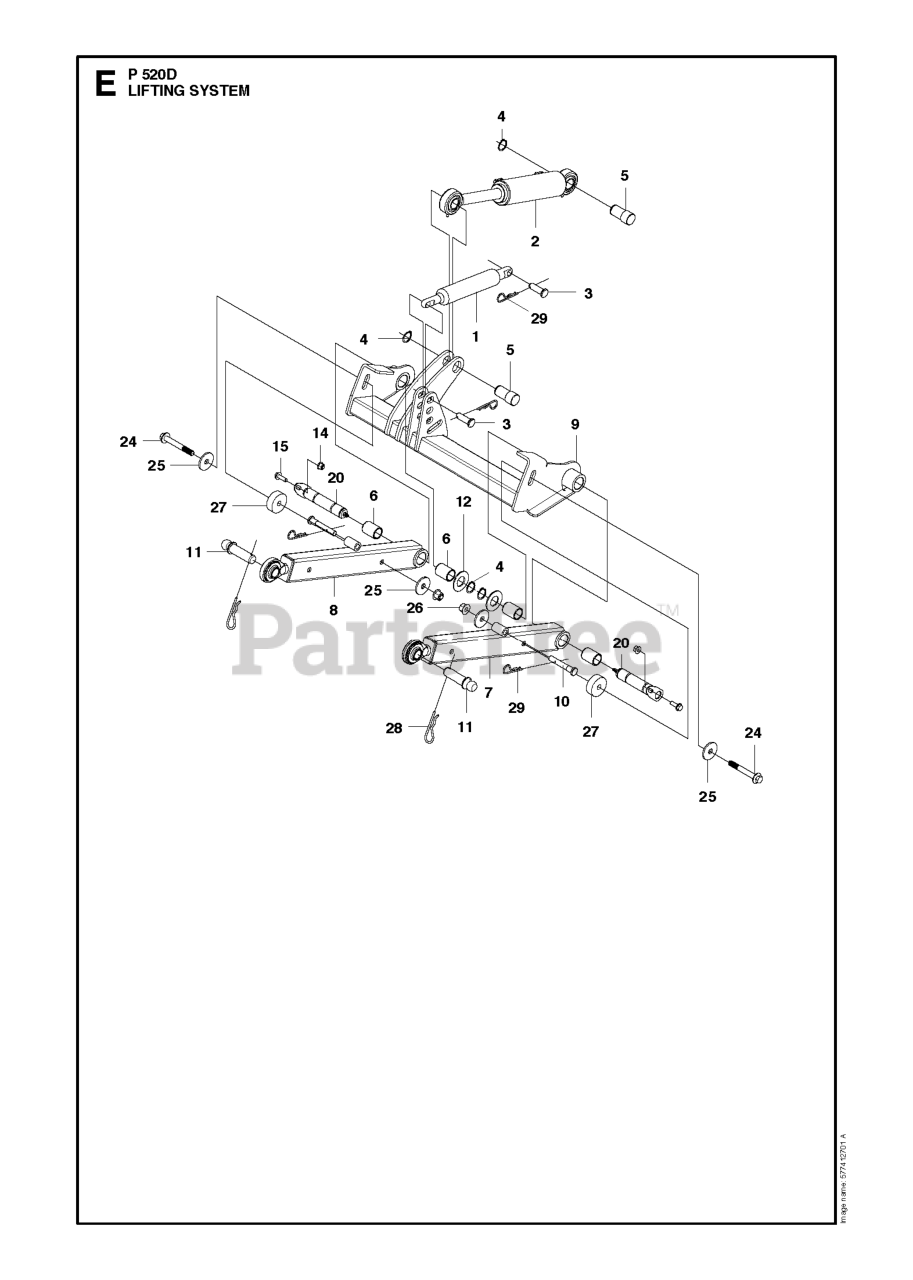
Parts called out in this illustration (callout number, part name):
3	CLEVIS PIN
11	BOLT LIFTING ARM
14	NUT FLANGE
15	BOLT
